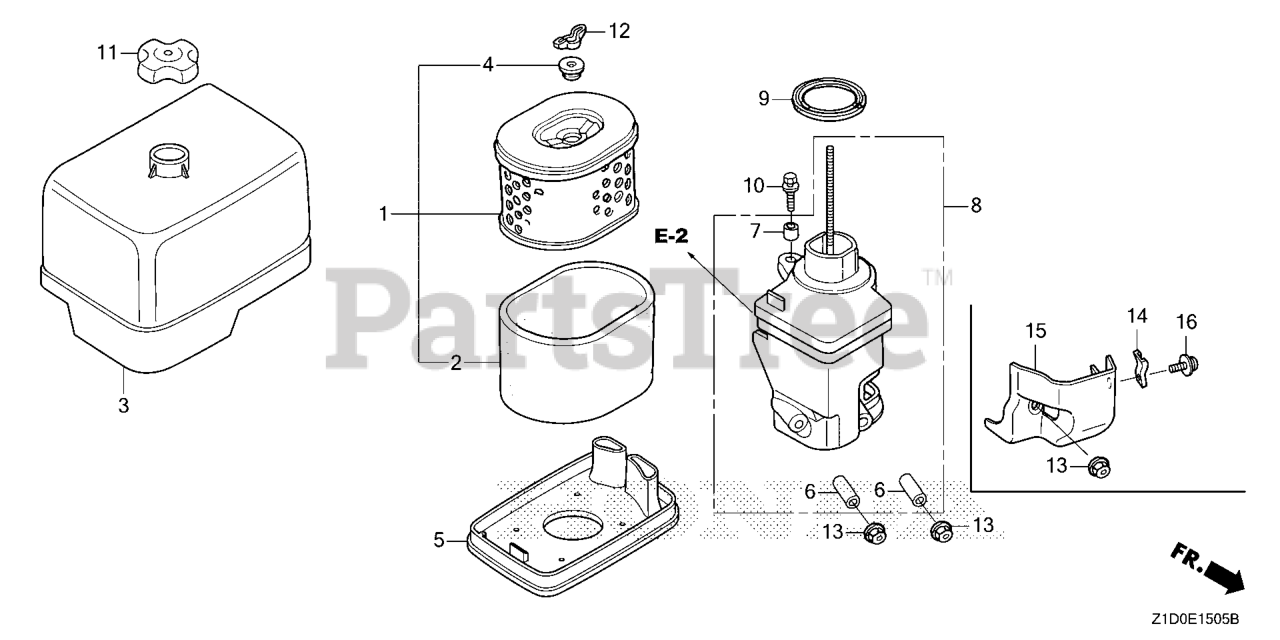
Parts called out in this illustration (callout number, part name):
1	ELEMENT, AIR CLEANER (DUAL)
2	FILTER (OUTER)
3	COVER, AIR CLEANER HOUSING
4	GROMMET, AIR CLEANER
5	NOSE, MUFFLER
6	COLLAR, AIR CLEANER
7	COLLAR B, AIR CLEANER
8	ELBOW, AIR CLEANER
9	GASKET, AIR CLEANER HOUSING
10	BOLT-WASHER (6X22)
11	NUT, AIR CLEANER COVER
12	WINGNUT, TOOL BOX SETTING
13	NUT, FLANGE (6MM)
